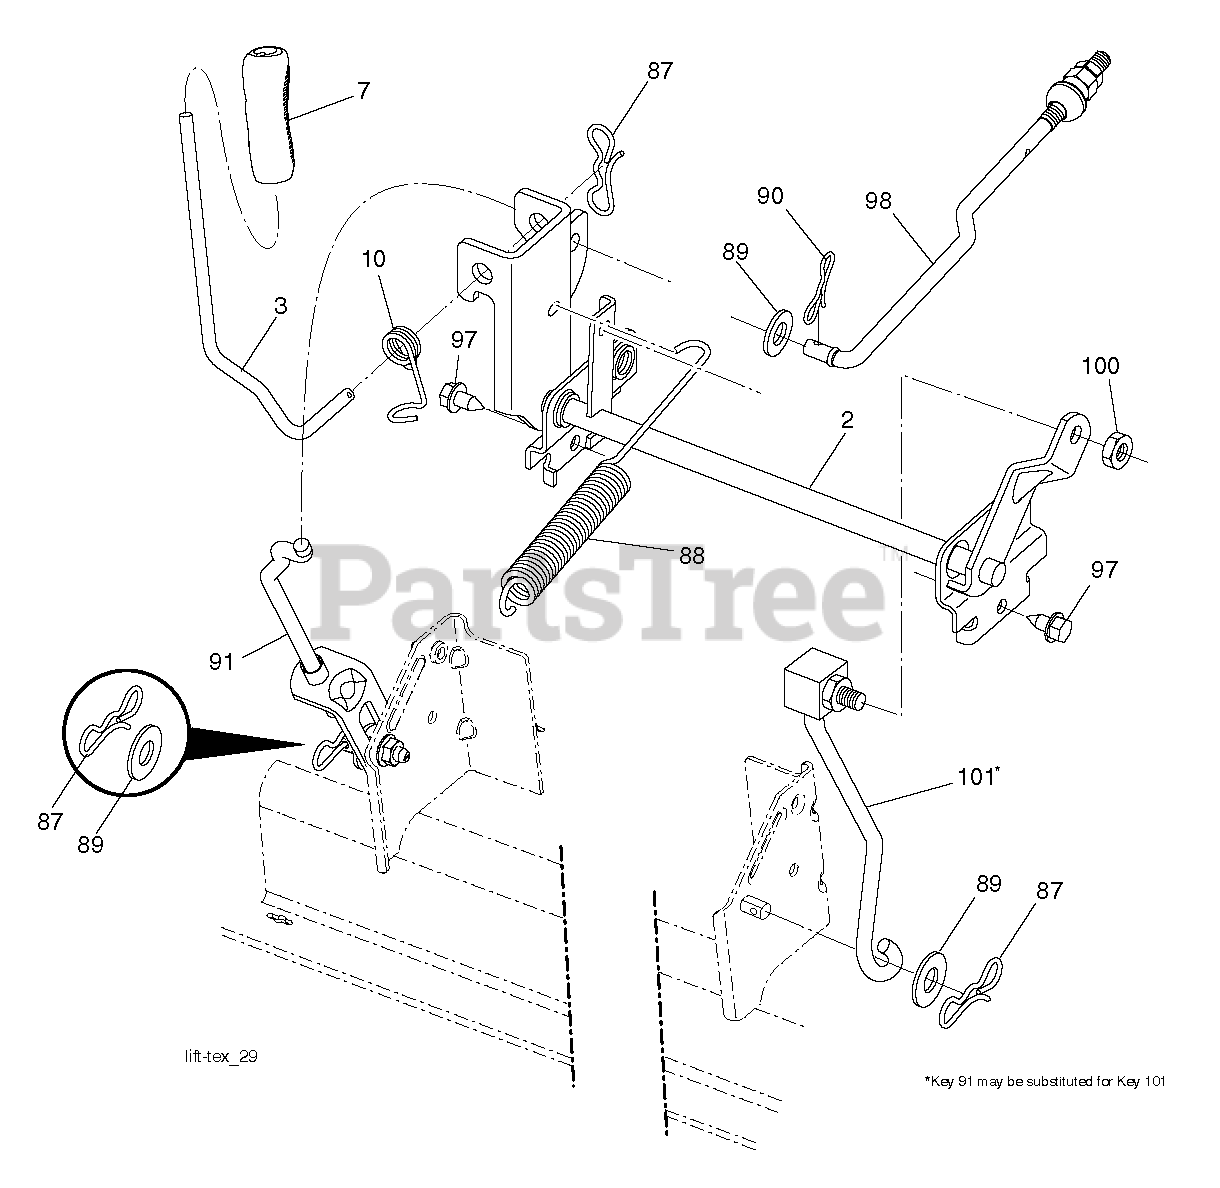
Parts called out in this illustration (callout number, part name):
2	SHAFT.ASM.CROSS.LIFT
3	LEVER.LIFT.HANDLE.LT
7	GRIP, LEVER
10	SPRING.TORSION.LIFT.HA
87	PIN.COTTER.7/16.BOW TI
88	SRPING.LIFT.ASSIST
89	WASHER.CLEAR.ZINC
90	PIN.COTTER.5/16.BOW TI
91	LINK.ASM.LIFT.REAR
97	SCREW, 3/8-16X3/4
98	LINK.ASM.SUSP.FRONT.MW
101	LINK.ASM.LIFT.FIXE.38/42/46"
